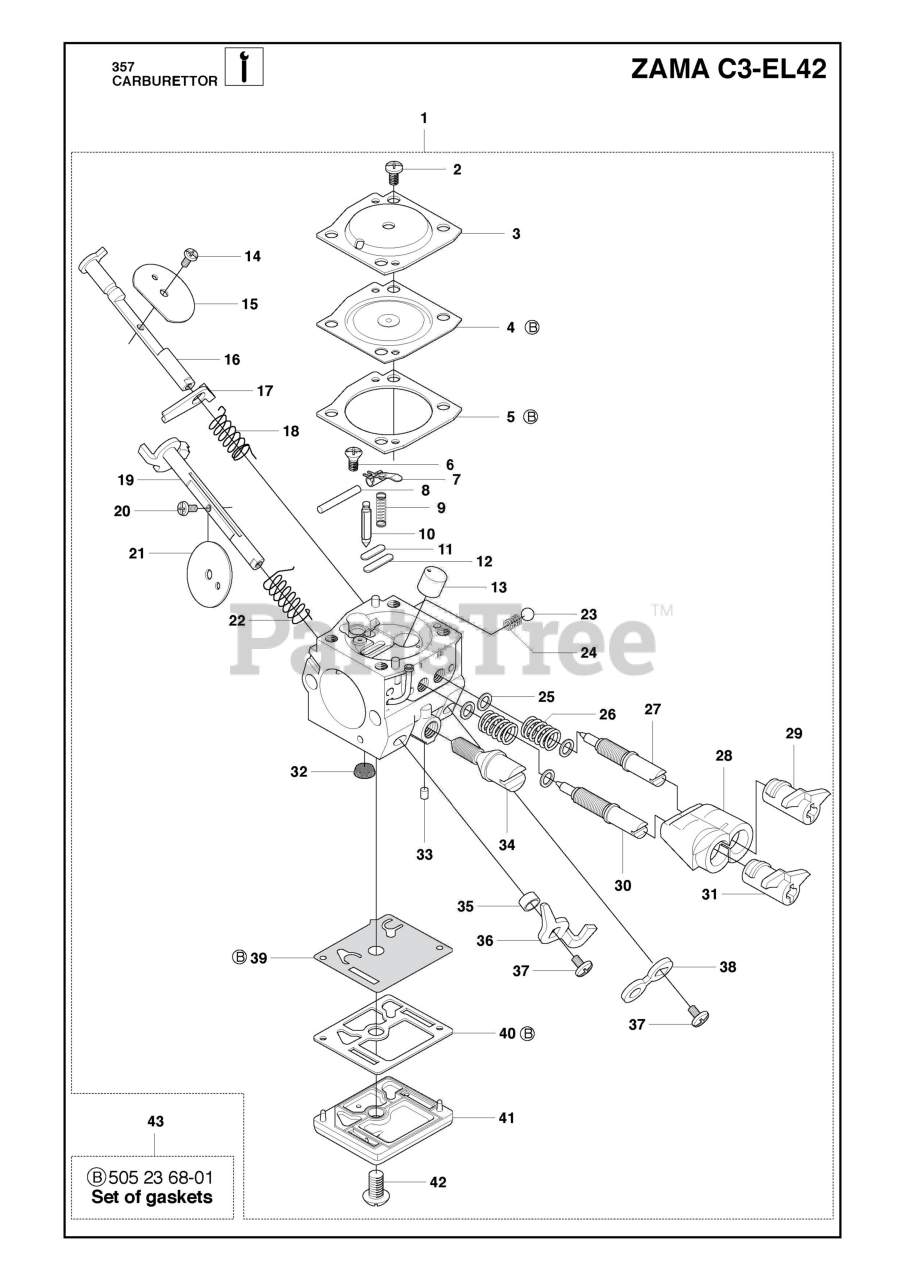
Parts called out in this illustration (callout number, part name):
1	RP CARBURETOR
8	PIN FULCRUM
13	NOZZLE ASSY
15	CHOKE FLAP
16	CHOKE SHAFT
17	THROTTLE LOCK
19	Throttle Shaft
21	THROTTLE FLAP
26	SPRING
29	LIMITER CAP
30	LOW SPEED NEEDLE
31	LIMITER CAP
39	PUMP DIAPHRAGM
43	KIT GASKET
